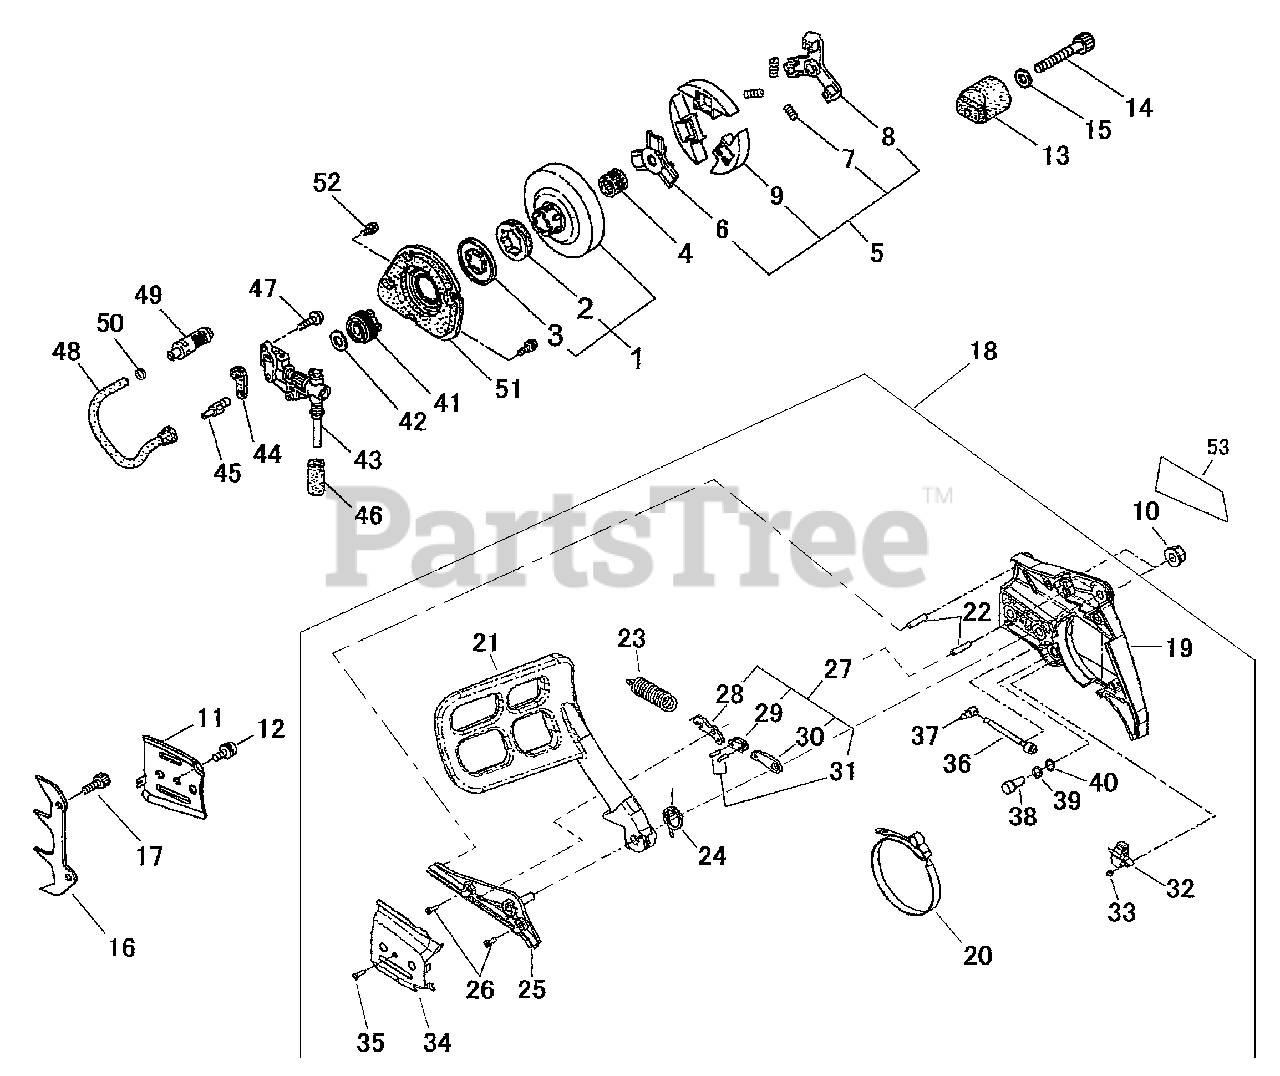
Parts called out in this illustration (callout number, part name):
1	DRUM ASSY, CLUTCH
2	SPROCKET, 0.325 RIM
3	COVER
4	BEARING, NEEDLE 10
5	CLUTCH ASSY
6	BOSS, CLUTCH A
7	SPRING, CLUTCH
8	BOSS, CLUTCH B
9	SHOE, CLUTCH
10	NUT 8
11	PLATE, GUIDE
12	SCREW M4×7
13	CHAIN CATCHER
14	BOLT M5×25
15	WASHER 5 MM
16	SPIKE, BUMPER
17	BOLT
18	COVER ASSY, CLUTCH
19	GUARD, SPROCKET
20	BAND, BRAKE
21	BRAKE, CHAIN
22	PIN, LOCATING Ø5×21.8
23	SPRING, COIL
24	SPRING, TORSION
26	SCREW, TAPPING 5×14
27	LEVER ASSY
28	LEVER, INNER
29	STRAP, TIE
31	PIN, TIE STRAP Ø3×11.8
32	COVER
33	SCREW, TAPPING 3×12
34	PLATE, GUIDE
35	SCREW, TAPPING
36	SCREW, SLIDE
37	PIN, SLIDE
38	GEAR
39	O-RING
40	WASHER Ø10.5ר7.5
41	GEAR
42	PLATE, THRUST
43	OIL PUMP ASSY
44	GASKET, OIL PUMP
45	ELBOW
46	FILTER
47	SCREW M4×16
48	PIPE, OIL
49	FILTER, OIL
50	CLIP, OIL FILTER
51	PUMP COVER, FLOCKED
52	SCREW
53	LABEL, MODEL - 490
